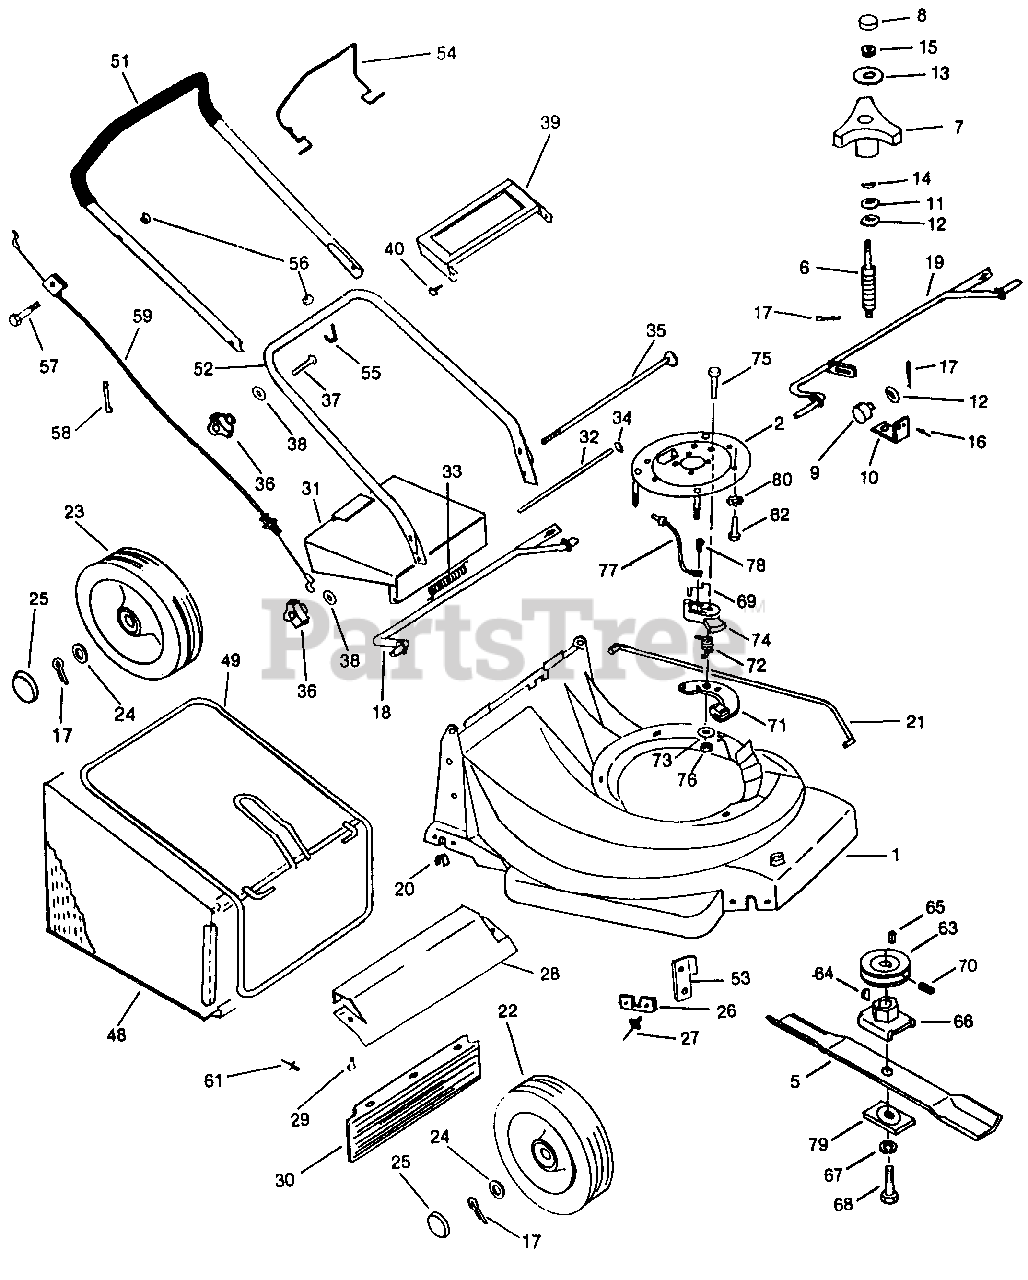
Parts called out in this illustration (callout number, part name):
1	Deck-16" Molded
2	Plate Assembly-Engine Mtg.
5	Blade-16"
6	Adjuster Screw
7	Knob-Height Adjust
8	Plug-Height Adjust Knob
9	Trunnion-Height Adjust
10	Bracket-Screw Brace
11	Washer
12	Washer
13	Washer
15	Nut-Metric
16	Blind Rivet 3/16"
17	Cotter Pin 3/32 x 3/4"
18	Rear Axle Assembly
19	Front Axle Assembly
20	Bushing-Axle
21	Link Rod
22	Wheel-6"
23	Wheel-7"
24	Fl-Wash. 3/8"
25	Hub Cap
26	Retainer-Front Axle
27	Blind Rivet 5/32"
28	Support-Deck & Trail Shield
29	Screw-Metric
30	Trail Shield
31	Rear Door Assembly
32	Hinge Pin
33	Spring-Rear Door
34	Retainer-Push Nut
35	Pin-Handle
36	Knob-Handle
37	Saddle Bolt
38	Saddle Washer
39	Trimplate
40	Screw #10 x 3/4"
48	Grass Bag
49	Frame Assembly-Grass Bag
51	Upper Handle w/Foam Grip
52	Lower Handle
53	Brace-Front Axle
54	Lever-Engine Control
55	Rope Guide
56	L-Nut 1/4-20 Thd.
57	Hex Bolt 1/4-20 x 1-1/4" *
58	Plastic Tie
59	Cable-Engine Control
61	Blind Rivet
62	Engine Mtg. Bolt
63	Pulley-Brake
64	Square Key
65	Woodruff Key #6
66	Adapter-Blade Mtg.
67	L-Wash. 3/8" I.D.
68	Blade Bolt
69	Spring-Contact
70	Set Scr. 5/16-18 x 3/8"
71	Arm Assembly-Brake
72	Spring-Brake Arm
73	Fl-Wash. 3/8"
74	Housing-Spring
75	Hex Bolt 3/8-16 x 1-3/4"
76	L-Nut 3/8-16 Thd.
77	Wire Assembly-Eng. Control
78	Screw #6-20 x 3/8"
79	Retainer Plate
80	Int. L-Wash. 5/16" I.D.
